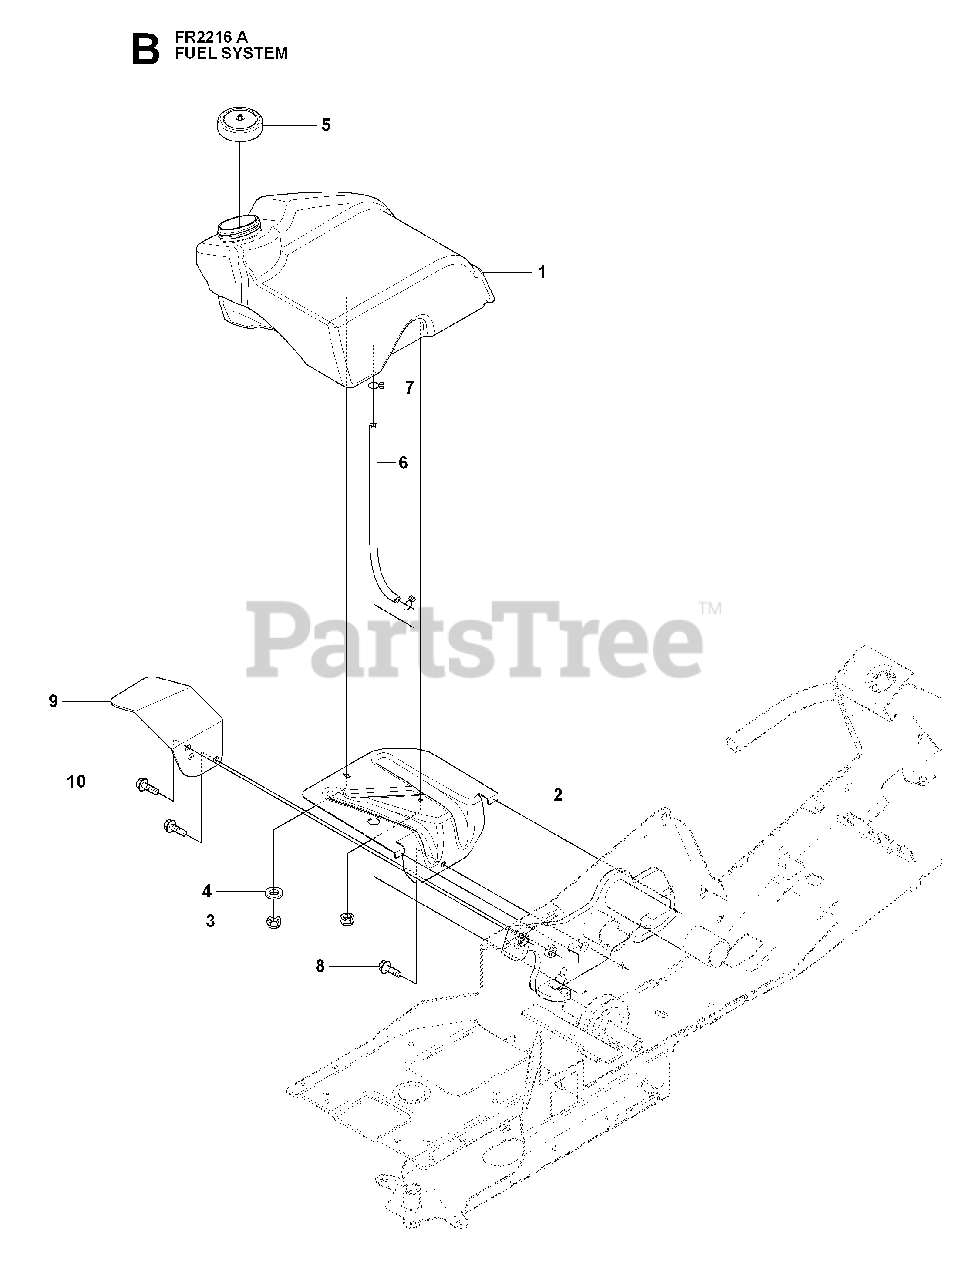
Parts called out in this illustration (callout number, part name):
3	LOCKNUT M6
4	WASHER
10	SCREW M10X25
